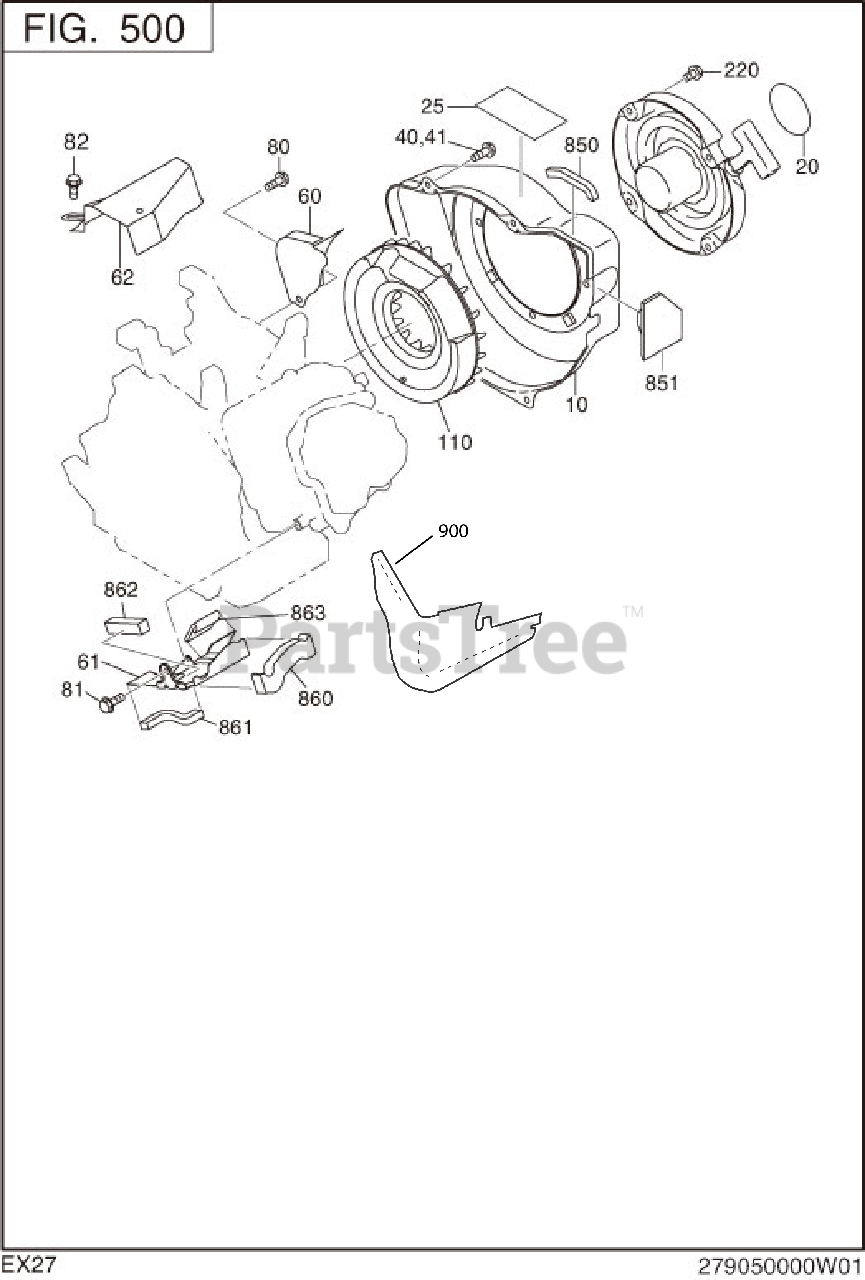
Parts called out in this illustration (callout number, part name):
10	BLOWER HOUSING CP
20	LABEL(TRADE MARK)
60	BAFFLE 1(CASE) CP
61	BAFFLE 2(HEAD)
